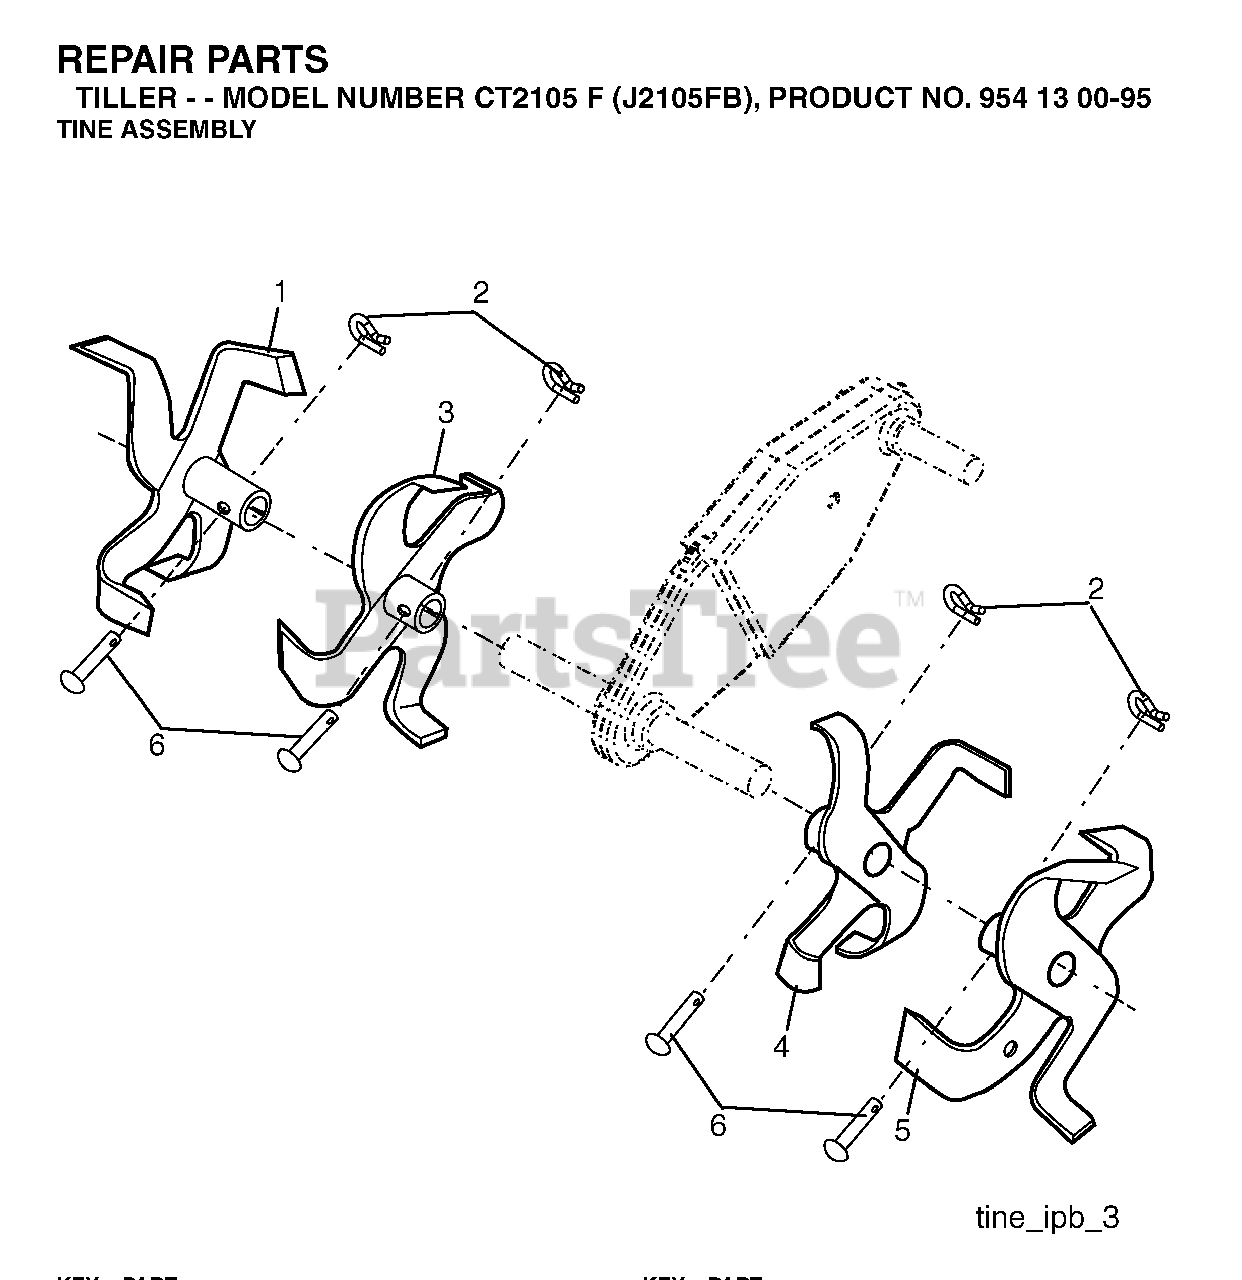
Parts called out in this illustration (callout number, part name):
1	RP TINE
2	SPRING RETAINER
3	RP TINE
4	RP TINE
5	RP TINE
